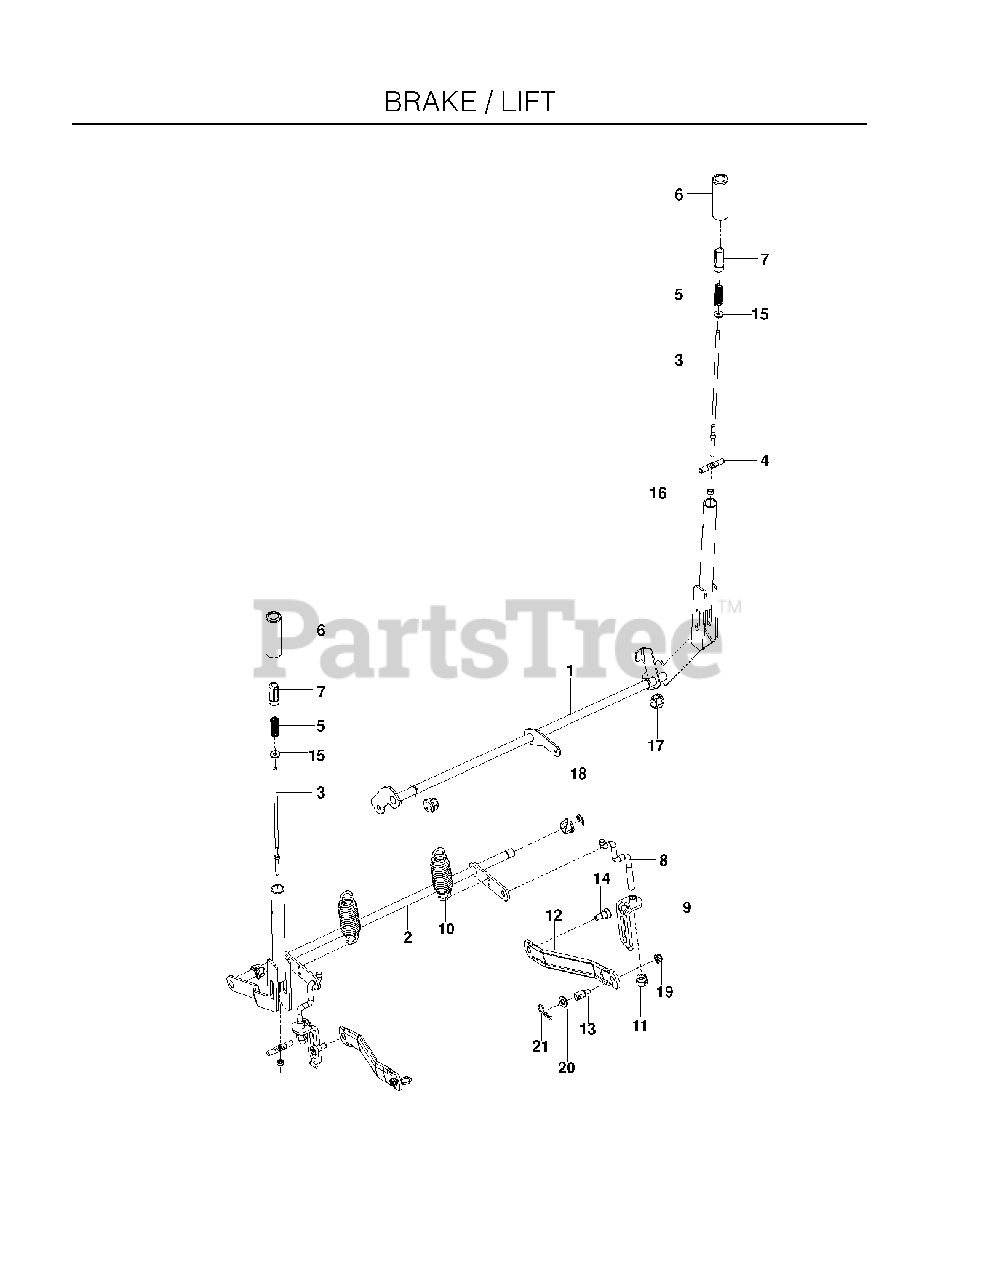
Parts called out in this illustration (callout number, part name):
1	SHAFT.ASSY.BRAKE.WLDMT.BLACK
2	SHAFT, LIFT, BLACK
3	ROD, HANDLE RELEASE
4	RB ROD, LATCH RELEASE
5	SPRING, COMPRESSION
6	GRIP, HANDLE, BLACK 4"
7	BUTTON, PUSH, BLACK
8	LINK, REAR SUSPENSION
9	ASSEMBLY, BRKT LINK
11	NUT, LIFT LINK 7/16-20
12	ARM.SUSPENSION.MOWER
13	STUD.FASTNER.W/ANTI-ROTATE
14	SB 3/8-16 X 3/8 SKT HD ZD
15	WASHER 1/4 FLAT
16	RP_NUT 1/4-20 NYLOC
17	PLASTIC NUT
18	E-RING 5/8
19	5/16-18 NYLOC FLANGE NUT
20	WASHER 5/8 FLAT
21	HAIRPIN #4
